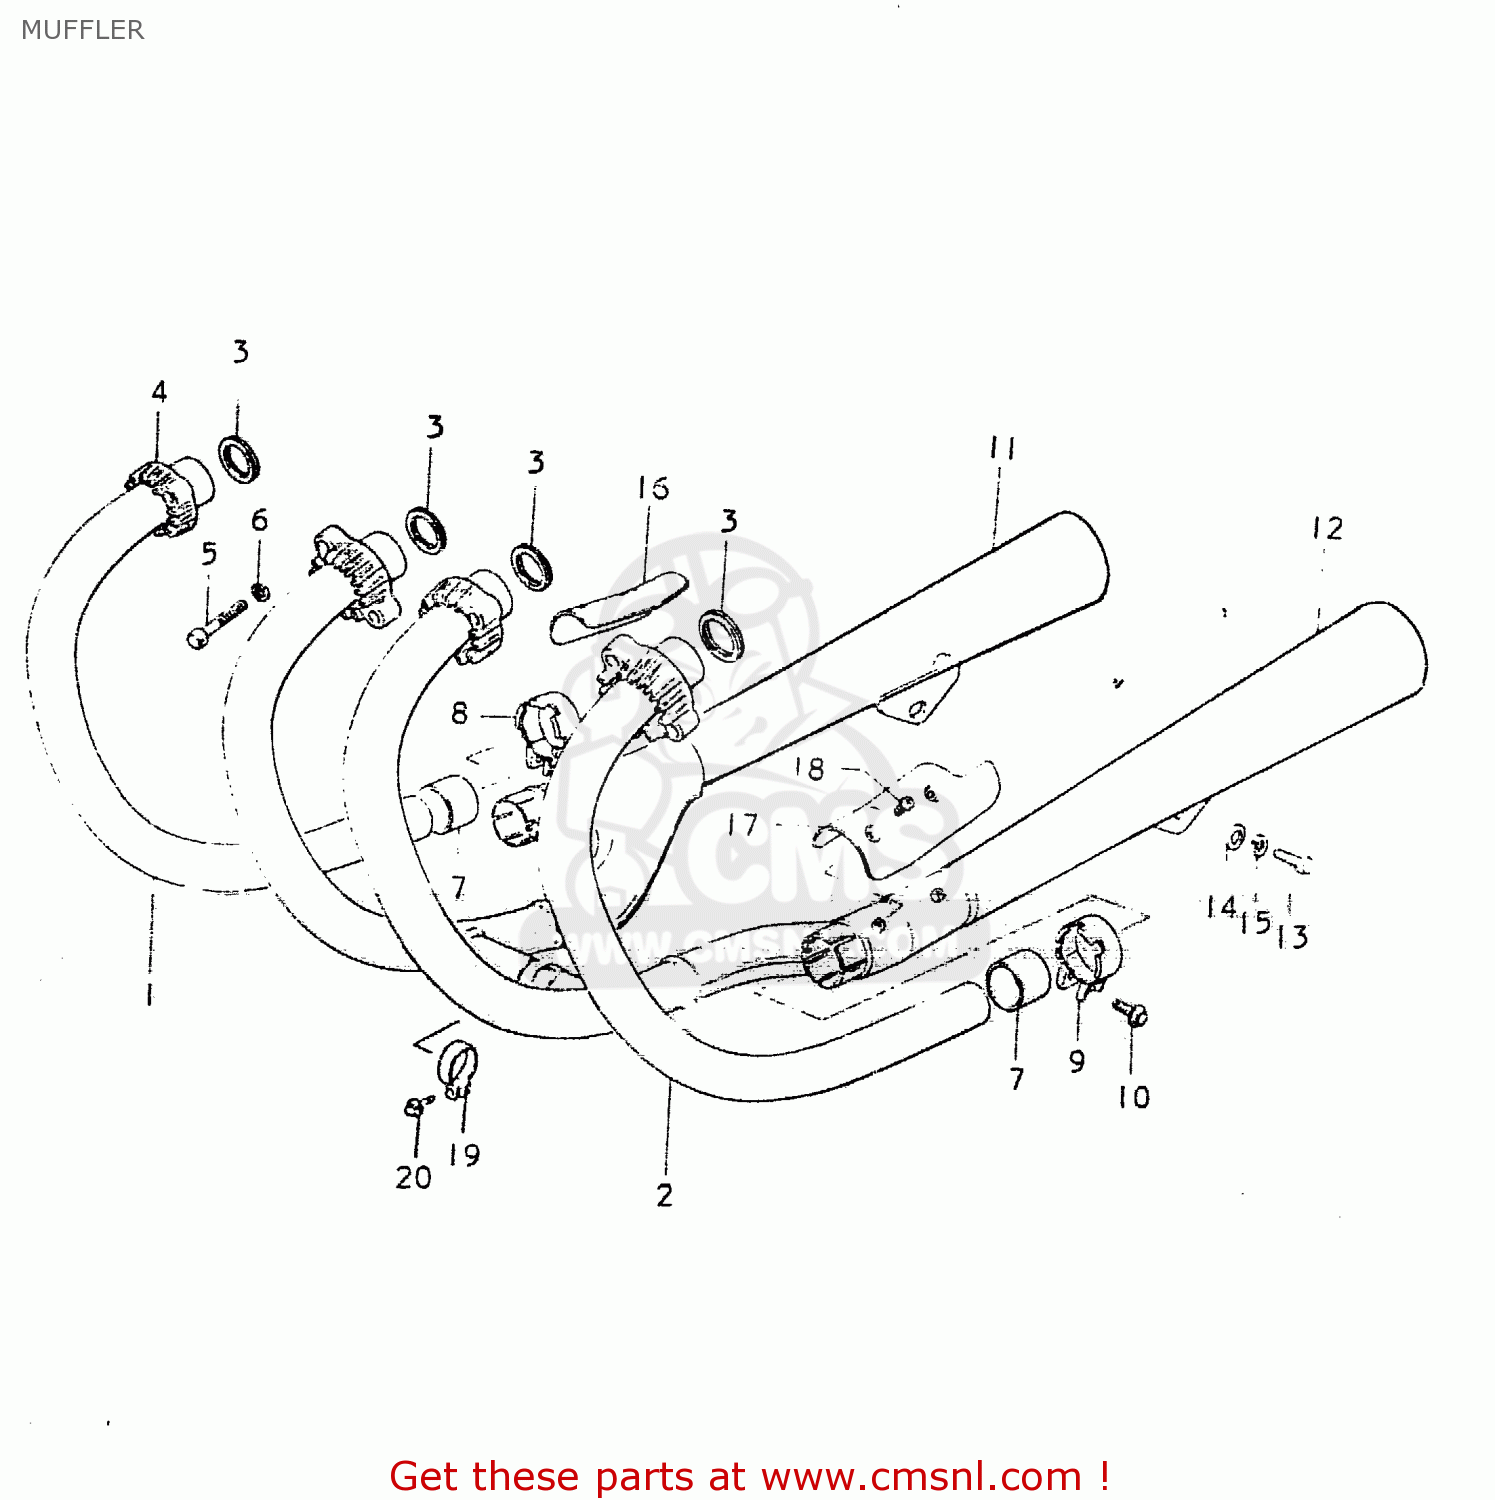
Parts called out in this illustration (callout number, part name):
1	PIPE,EXHAUST,RIGHT
2	PIPE,EXHAUST,LEFT
3	GASKET,EXHAUST PIPE (NAS)
4	CLAMP,EXHAUST PIPE
5	BOLT
6	LOCK WASHER
7	CONNECTOR,MUFFLER
8	CLAMP,MUFFLER CONNECTOR,R
9	CLAMP,MUFFLER CONNECTOR,L
10	BOLT
11	MUFFLER, RH
12	BODY,MUFFLER
13	BOLT 10X30
14	WASHER
15	LOCK WASHER
16	COVER,MUFFLER,RIGHT
17	COVER,MUFFLER,LEFT
18	SCREW
19	CLAMP,EXHAUST COUPLER
20	BOLT,REAR
